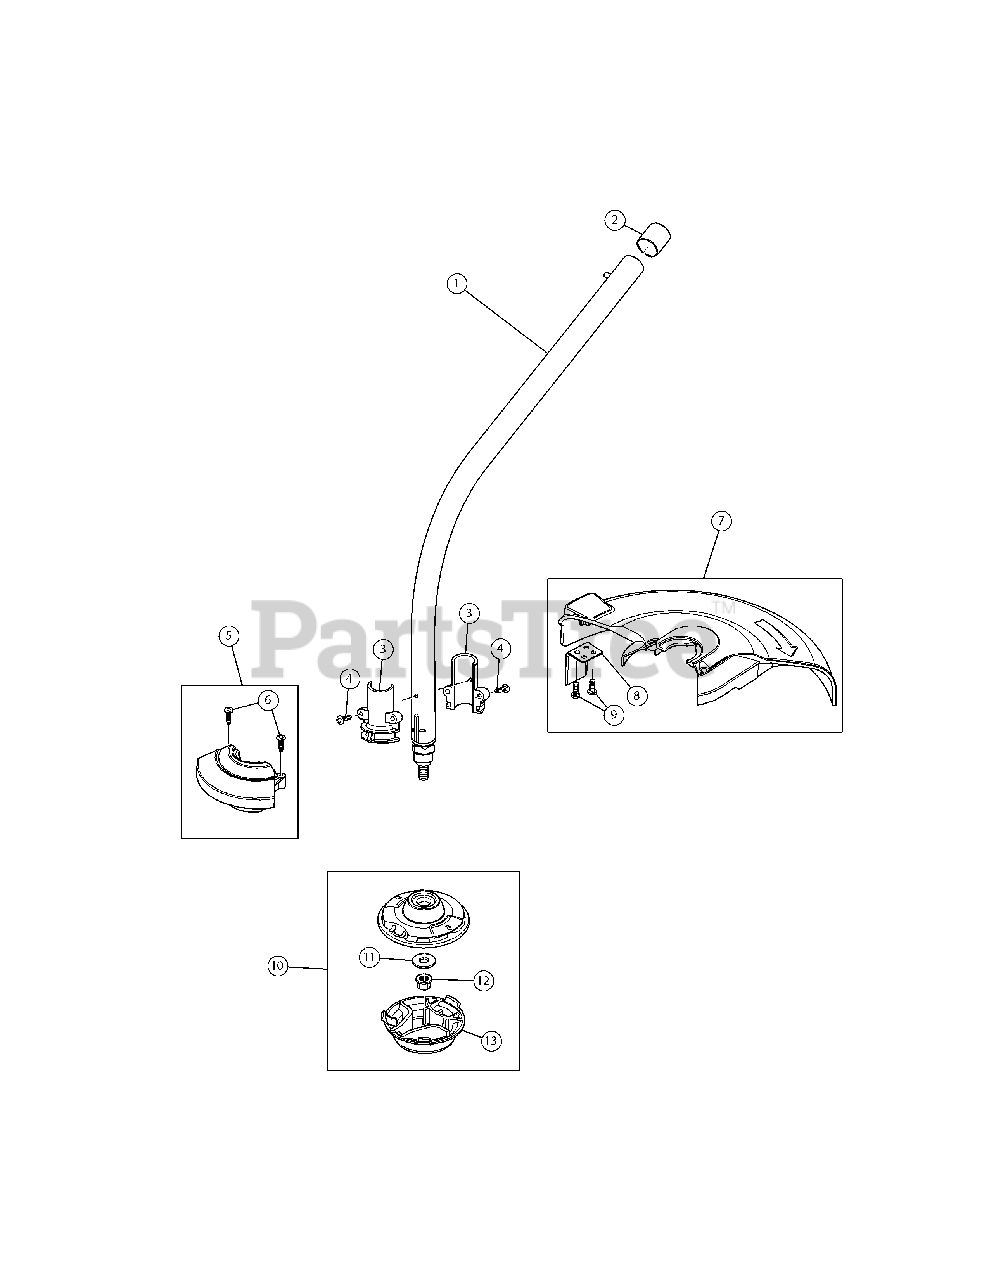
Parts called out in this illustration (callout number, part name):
1	Lower Drive Shaft Housing Assembly
3	Hub Guard Assembly
5	Front Shield Assembly
7	Rear Shield Assembly
8	Blade Assembly
10	Cutting Head Assembly
11	Washer
12	Cutting Head Nut
